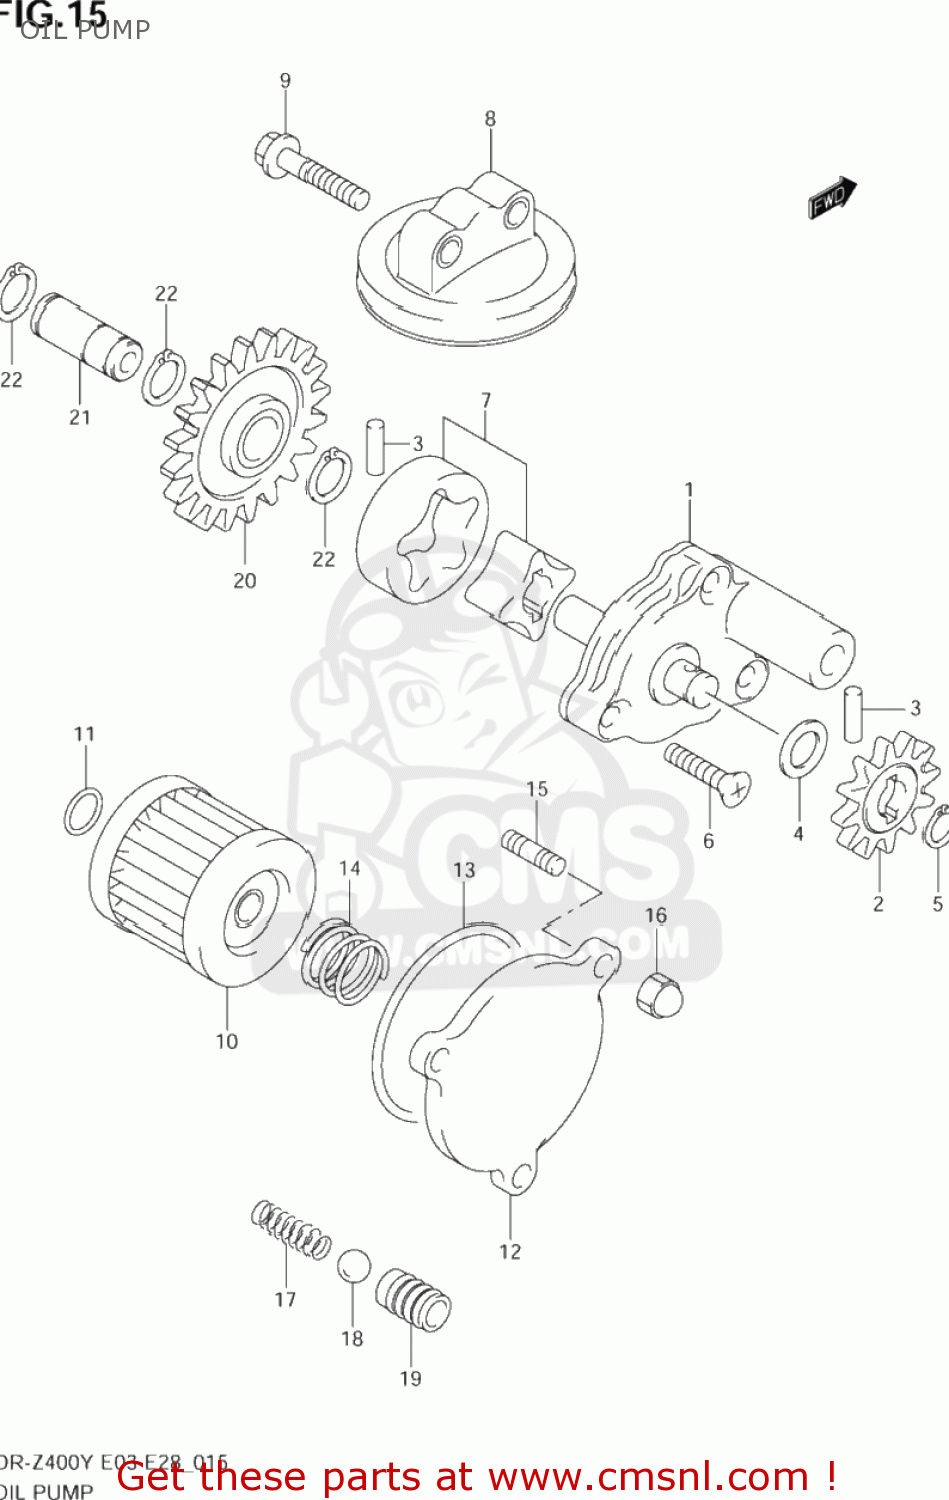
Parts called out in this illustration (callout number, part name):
1	PUMP ASSY,ENGINE OIL NO.1
2	GEAR,OIL PUMP DRIVEN
3	PIN(4X15.8)
4	SHIM(10X18X0.5)
5	CIRCLIP,10MM
6	SCREW
7	ROTOR SET,OIL PUMP,NO.2
8	STRAINER,OIL PUMP NO.2
9	BOLT
10	FILTER ASSY,ENGINE OIL
11	O RING(D:1.9,ID:13)
12	CAP,OIL FILTER
13	O RING(D:2.4,ID:52.6)
14	SPRING
15	BOLT,STUD
16	NUT
17	SPRING
18	BALL
19	SEAT,OIL CHECK VALVE
20	GEAR,OIL PUMP IDLE
21	SHAFT,OIL PUMP IDLE GEAR
22	CIRCLIP,12 MM
